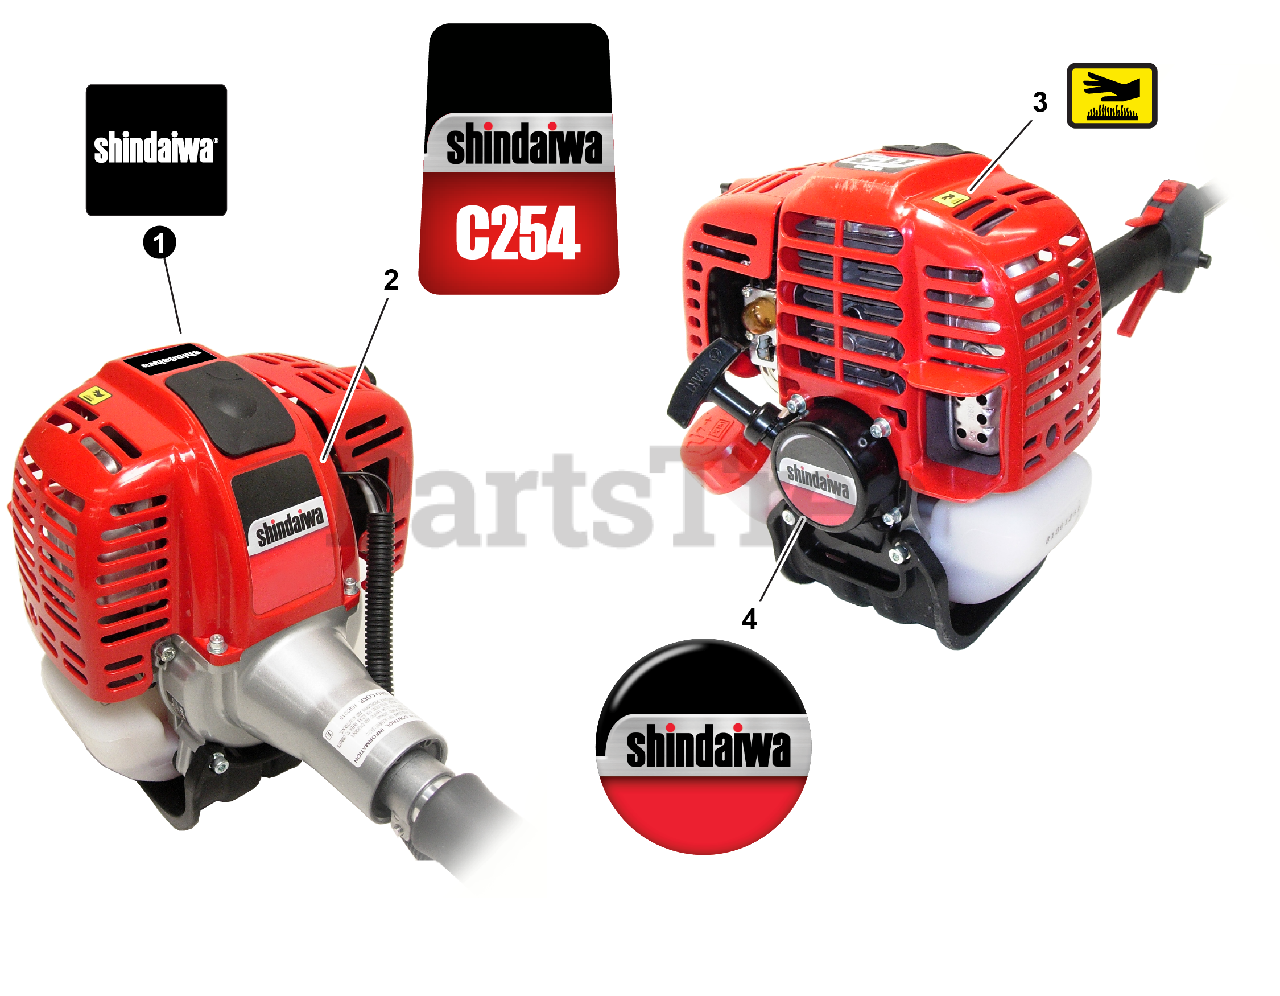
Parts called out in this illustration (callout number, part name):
1	LABEL, shindaiwa
2	LABEL, C254
3	LABEL, CAUTION - HOT
4	LABEL, RECOIL STARTER
